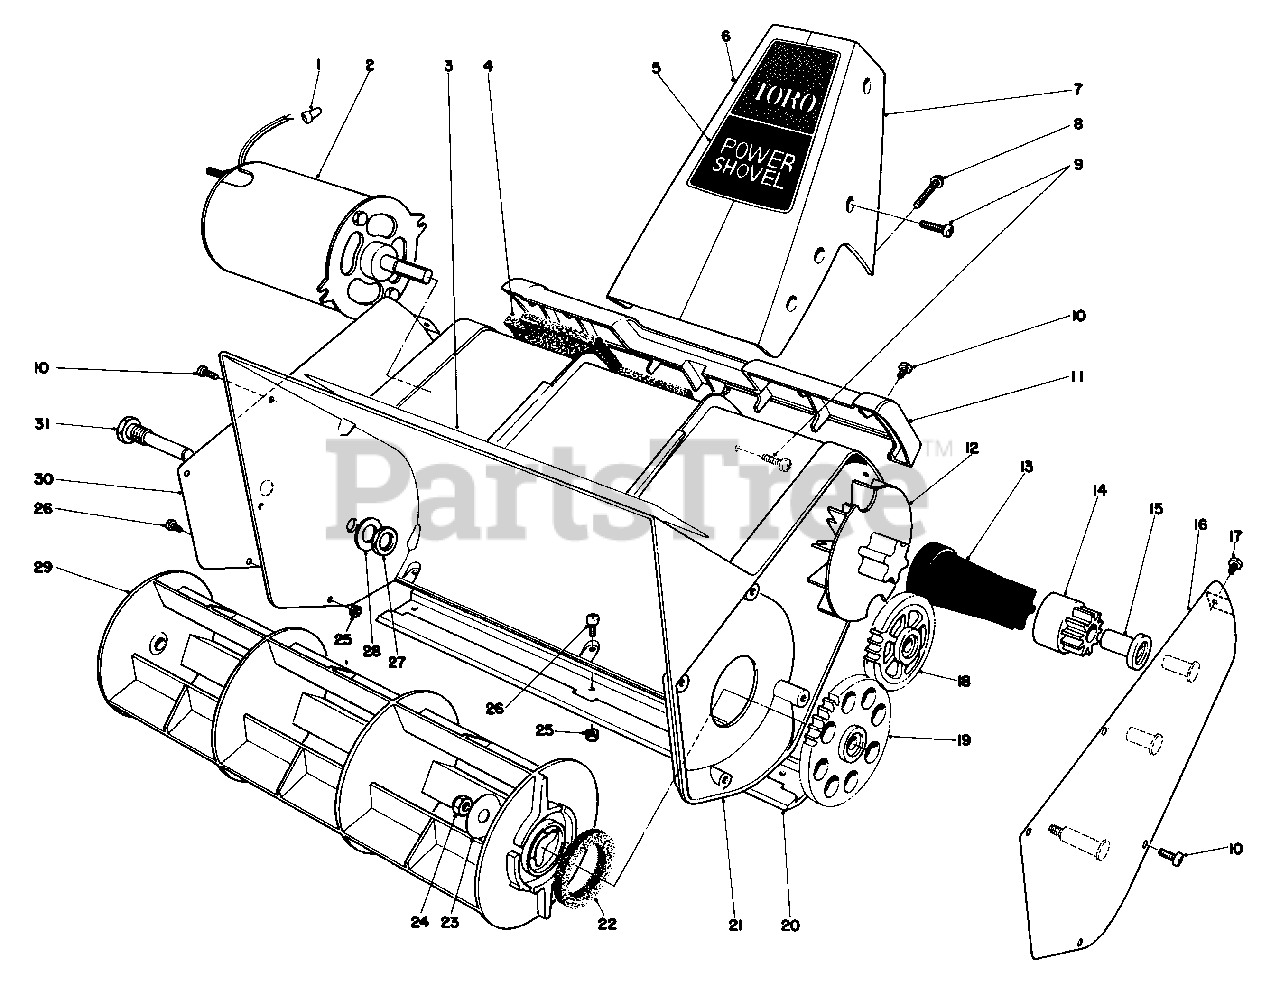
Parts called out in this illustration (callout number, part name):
1	Wire Connector
2	Electric Motor
3	Decal-U.L.
4	Foam Filter
5	Decal-Handle Support
6	Handle Support R.H.
7	Handle Support L.H.
8	Plastite Screw
9	Plastite Screw
10	Plastite Screw
11	Deflector
13	Drive Coupling
14	Pinion Assy. (Incl. Ref. #15)
15	Bushing-Gear
16	Gear Carrier
17	Taptite Screw
18	Idler Gear
19	Rotor Gear (Incl. Ref. #15)
22	Washer-Felt
23	Washer-Steel
27	Locknut
30	Cover, Right
31	Pin, Rotor
